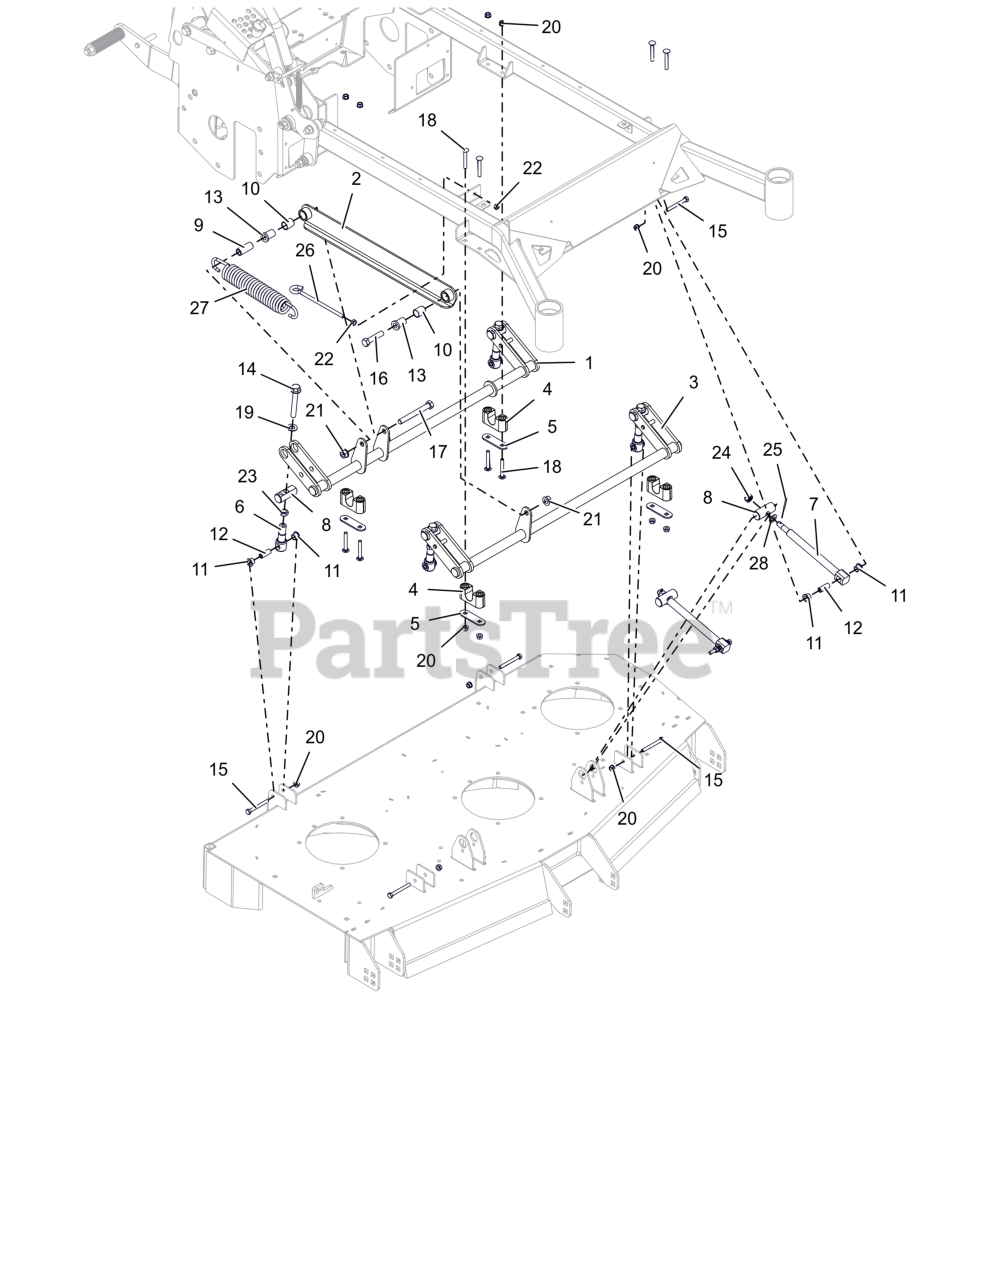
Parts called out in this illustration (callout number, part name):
1	WLDMT- DECK LIFT
2	LINK- DECK LIFT (BLACK)
3	WLDMT- DECK LIFT - FRONT
4	ASM-BUSHING, DECK LIFT
5	PLATE, BEARING SUPPORT
6	LINK, DECK LIFT FORMED
7	DRAG,LINK-HD
8	PIN, DECK LIFT
9	BUSHING- .515 X 1.000 X 3.088
10	BRG- .750 X .875 X 1.000
11	BSHG, FLANGED .50X.625X.50X.062
12	SPCR, .31X.50X1.265
13	BSHG-FLG .515X.746X1.290X1.000
14	BLT, .500-13 X 3.500 GR5 ZC
15	BLT, HEX .31-18X2.75 G5 ZCC
16	BLT, HEX .50-13X2.25 G5 ZCC
17	BLT, HEX .50-13X4.25 G5 ZCC
18	BLT, RHSSN.31-18X2.25 G5 ZCC
19	WSHR, FLT .557X1.040X.102 ZCC
20	NUT,LK-CTR-FLG .31-18 GF ZCC
21	NUT-LK-CTR-FLG .500-13 GG ZCC
22	NUT-JAM .375-16 G2 ZCC
23	NUT-JAM .500-13 G2 ZCC
24	NUT-SL .50-13
25	PIN,CTR.12X1.25EXTPRSQCT ZC120
26	BOLT, .38-16X6.00 .62 DIA EYE
27	SPRG-EXTEN - .273X1.853X10.125
28	WSHR, BLVL .531 X 1.000 X .062 MZ
